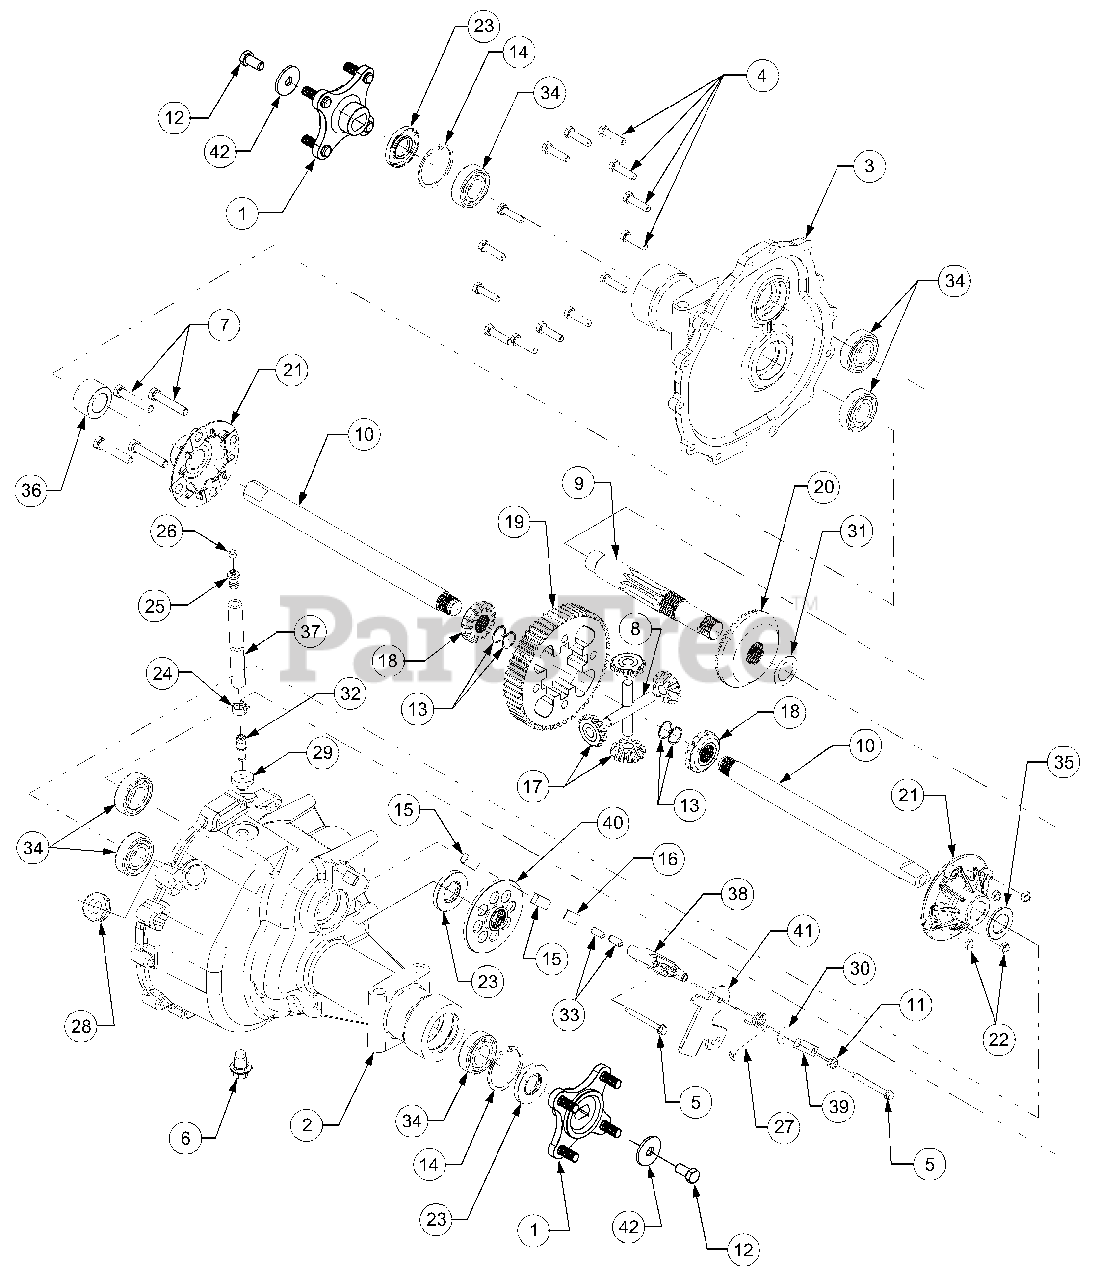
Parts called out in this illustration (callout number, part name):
1	Hub Assembly, Wheel
2	Housing, RH Transmission
3	Housing, LH Transmission
4	Screw, Hex Cap Lock, 5/16-18 x 1.25 GR5
5	Screw, Hex Wash Hd. Tapp, 1/4-20 x 2.375
6	Screw, Plug, M14 x 1.5 x .827
7	Screw, Hex Cap Lock, 3/8-16 x 2.0 GR5
8	Shaft, Cross, .50 x 3.005
9	Shaft, Output, 9T
10	Shaft, Axle
11	Nut, Hex Nylon Lock, 5/16-24
12	Screw, Hex Cap Lock, 3/8-16 x .75 GR5
13	Ring, Retaining
14	Ring, Retaining
15	Pad, Brake
16	Plate, Puck
17	Gear, Miter, 10T
18	Gear, Miter, 14T
19	Gear, Differential Spur, 60T
20	Gear, Bevel, 54T
21	Housing, Differential w/Thru Holes
22	Nut, Hex Insert Jam GR5, 3/8-16
23	Seal, Oil, 1.0 x 2.047 x .2755
24	Clamp, Hose
25	Vent, Plastic
26	Cap, Plastic Vent
27	Spring, Torsion
28	Grommet, Rubber, .75 x 1.063
29	Grommet, Rubber, .362 x .56
30	Washer, Flat, .343 x .88 x .062
31	Washer, Thrust, 1.007 x 1.542 x .03
32	Fitting, Tube
33	Pin, Brake Actuating
34	Bearing, Ball (6205-1)
35	Spacer, Axle, 1.007 x 1.665 x .141
36	Spacer, Axle, 1.007 x 1.665 x .989
37	Tube, Transmission Breather
38	Yoke, Brake
39	Bracket, Brake Anti Rotation
40	Disc, Brake
41	Arm, Brake Actuater
42	Washer, Flat, .39 x 1.5 x .134
